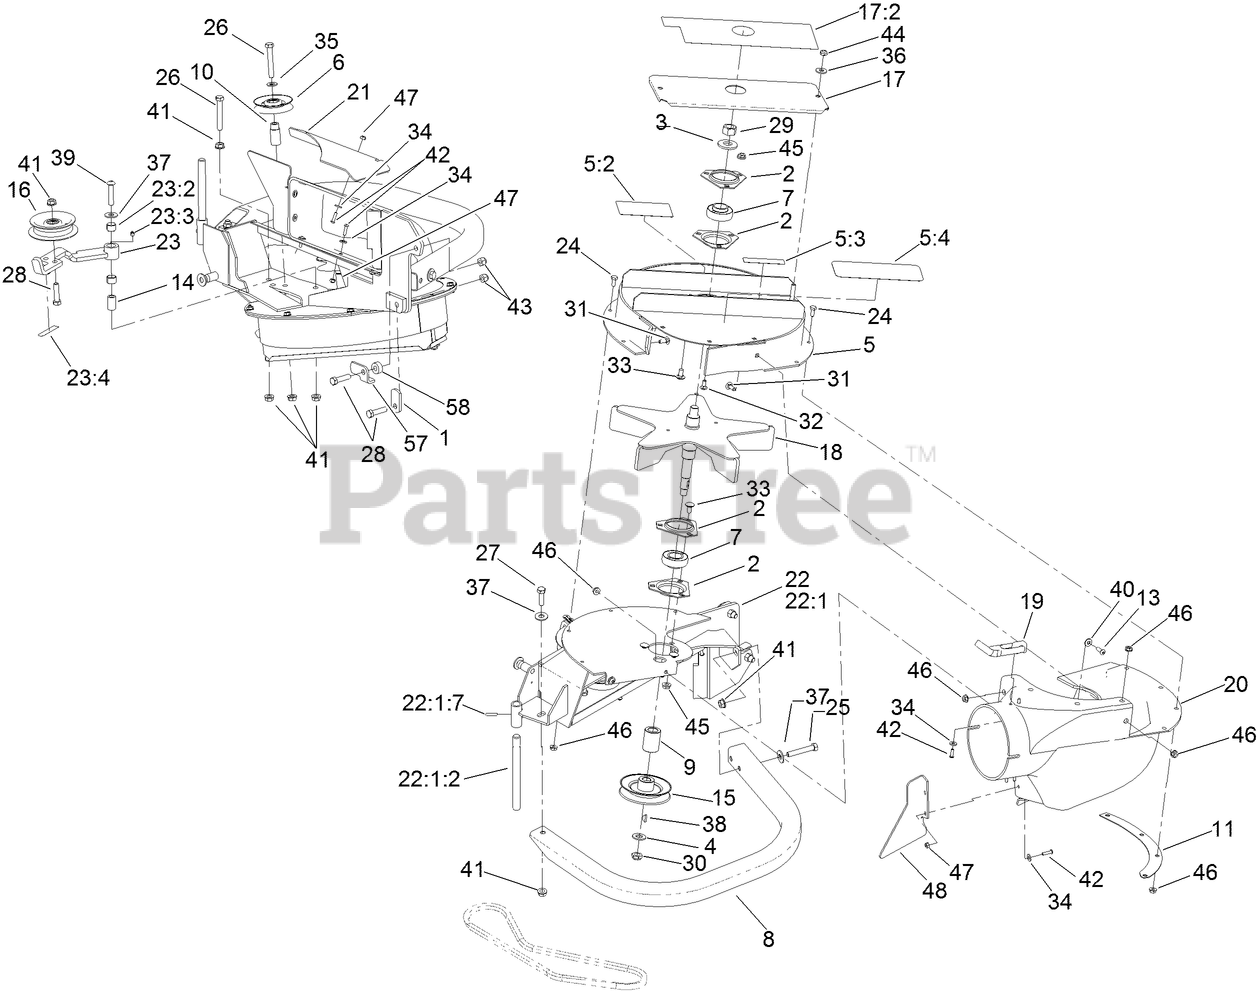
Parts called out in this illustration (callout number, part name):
1	LATCH-CATCHER, GRASS
2	HOUSING-FLANGE
3	WASHER-SPRING
4	WASHER-FLAT
5	UPPER HOUSING ASM
5:2	DECAL-WARNING
5:3	DECAL-COVER, MISSING
6	IDLER-INSIDE
7	BEARING
9	SPACER
11	PLATE-BACKING, BLOWER
13	SCREW-HSBH
14	BUSHING-PIVOT, IDLER
15	PULLEY
16	IDLER-FLAT
17	BEARING COVER ASM
17:2	DECAL-WARNING
18	IMPELLER
19	LATCH-RUBBER
20	CHUTE-BLOWER, SMALL
21	PLATE-BOTTOM
22	BLOWER MOUNT ASM
22:1	BLOWER-MOUNT
22:1:2	SHAFT-CATCHER, GRASS
22:1:7	PIN-ROLL
23	IDLER ARM ASM
23:2	BUSHING
23:3	FITTING-GREASE
23:4	DECAL-WARNING
24	SCREW-HH
25	SCREW-HH
26	SCREW-HH
27	SCREW-HH
28	SCREW-HH
29	NUT-HEX
30	NUT-LOCK, NI
31	BOLT-CARR
32	SCREW-CARR
33	SCREW-CARR
34	WASHER-FLAT
35	WASHER-FLAT
36	WASHER-FLAT
37	WASHER-FLAT
38	KEY-WOODRUFF
39	SCREW-HSBH
40	WASHER-FLAT
41	NUT-HHF, WHIZ
42	SCREW-HSBH
43	NUT-LOCK, NI
44	NUT-LOCK, NI
45	NUT-HF
46	NUT-HF
47	NUT-LOCK, NI
48	PLATE-FILLER, REAR
57	LATCH-STOP
58	SPACER
